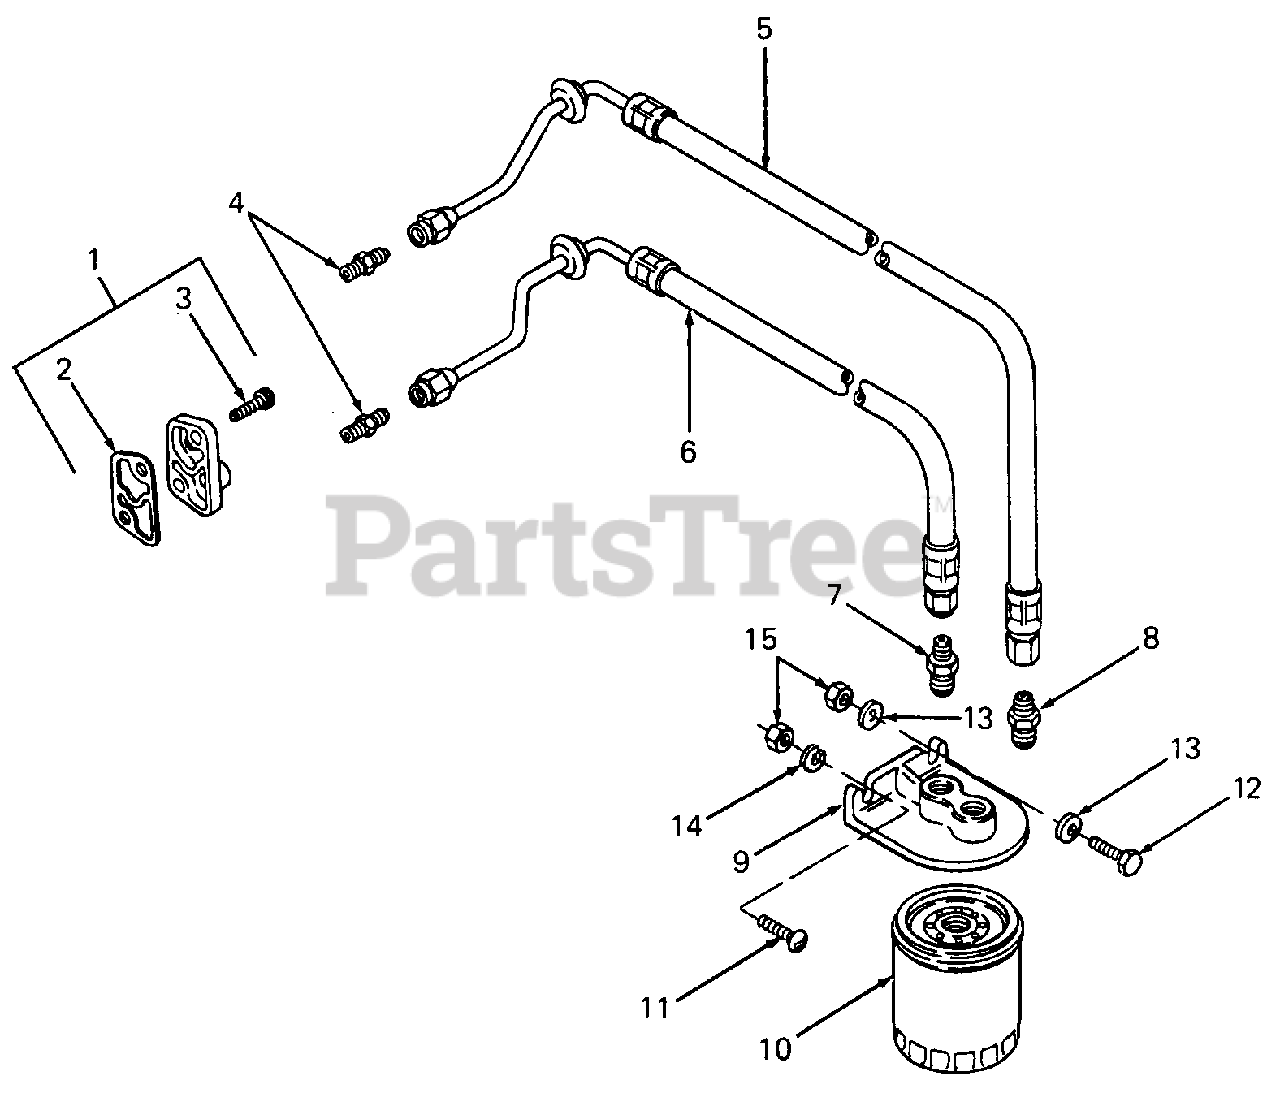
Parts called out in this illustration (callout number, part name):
1	Kit, Oil Filter Cover
2	Gasket, Oil Filter Cover
3	Screw, Hex Socket Hd Cap, 5/16-18 X 1.25 Lg
4	Connector, Reducing
5	Oil Line - 20.5 Long
6	Oil Line - 19.0 Long
7	Connector, Reducing
8	Nipple, Hexagon
9	Adapter, Remote Oil Filter
10	Oil Filter
11	Screw, Truss Hd Machine, 5/16-18 X .75 Lg GR5
12	Screw, Hex Cap, 5/16-18 X .75 Lg GR5
13	Washer, Bell, .380 X .88 X .060 Thk
14	Washer, Lock, 5/16
15	Nut, Hex, 5/16-18 GR5
